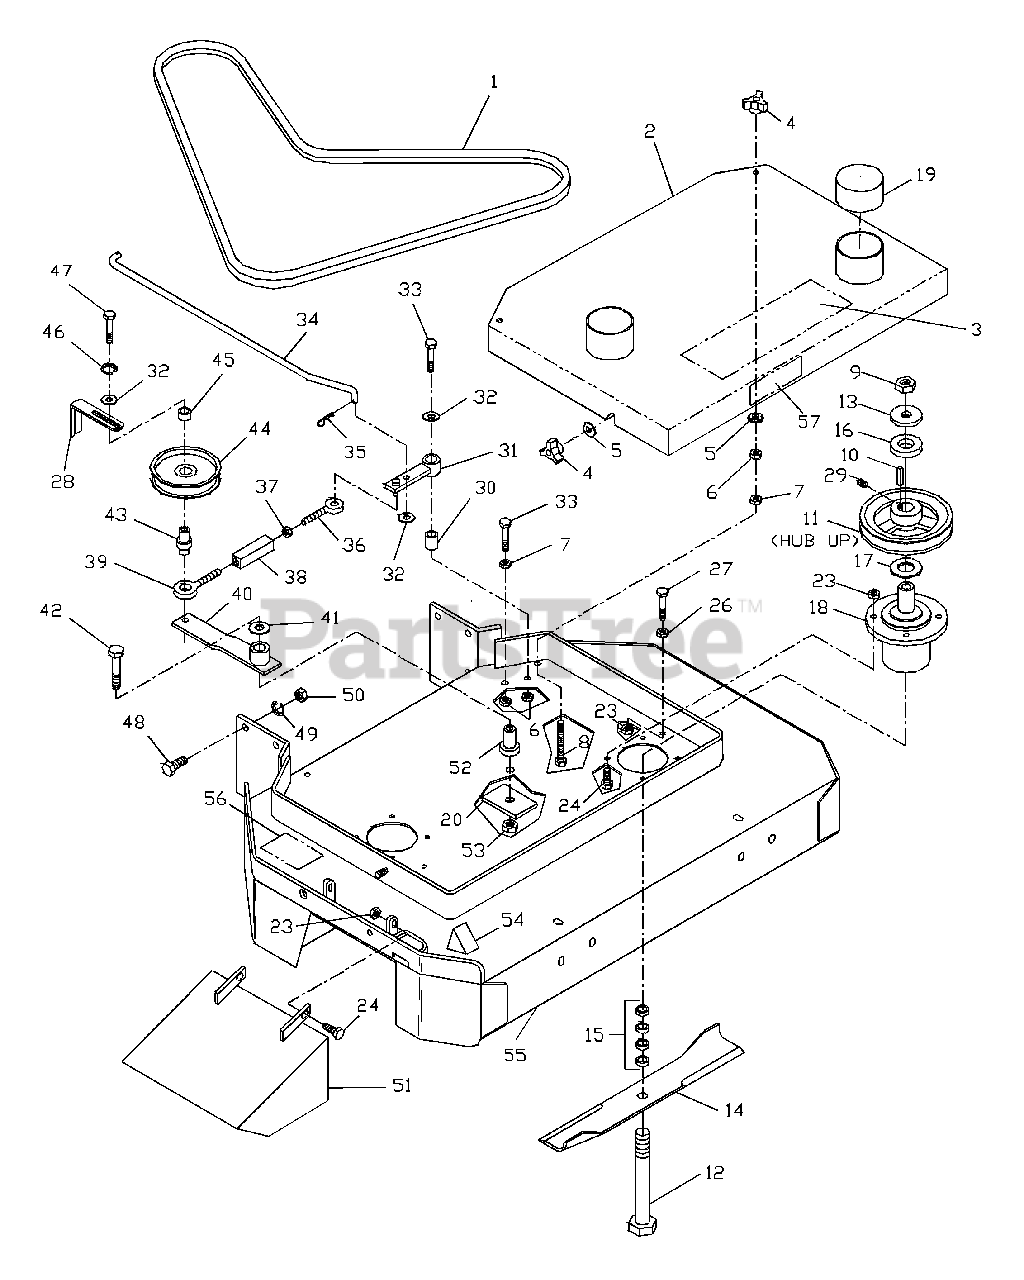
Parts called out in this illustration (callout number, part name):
1	36" DECK BELT
1	32" DECK BELT
2	36" BELT SHIELD
2	32" BELT SHIELD
3	DECAL, HUSQVARNA
4	THREE PRONG KNOB
5	3/8 SEALING WASHER
7	3/8C WHIZ NUT
8	TAP BOLT 3/8C X 4 1/2
10	KEY 1/4SQ. X 1 1/8
11	PULLEY W/SETSCREWS
12	HCS 5/8F X 8 1/2
13	SUPPORT WASHER
14	BLADE 18"
14	BLADE 16 1/4"
15	BLADE SPACERS
17	MACH. BUSHING 10GA.
18	HOUSING ASM.
20	PAD
24	HCS 5/16C X 1
26	HFLN 5/16C
27	HCS 5/16C X 3
29	5/16 NYLOC SETSCREW
30	SLEEVE BUSHING
31	ENGAGEMENT ARM
32	FW 3/8 STD
33	HCS 3/8C X 2 1/4
34	BLADE ROD
35	#2 HAIRPIN
36	RT. HAND EYEBOLT
37	5/16C HEX NUT
38	TURNBUCKLE
39	LT. HAND EYEBOLT
41	FW 1/2 STD
42	HCS 1/2C X 2 3/4
43	EYEBOLT PIVOT
44	IDLER PULLEY
46	3/8 LOCK WASHER
47	HCS 3/8C X 2 1/2
48	HCS 7/16C X 1 1/2
49	7/16 LOCK WASHER
50	7/16C HEX NUT
51	DEFLECTOR CHUTE
52	IDLER SPINDLE
53	HLN 1/2C NYLOC
54	DECAL, CPSC
55	36" DECK W/DECALS
55	32" DECK W/DECALS
56	DECAL, DANGER
57	DECAL, NASCAR
